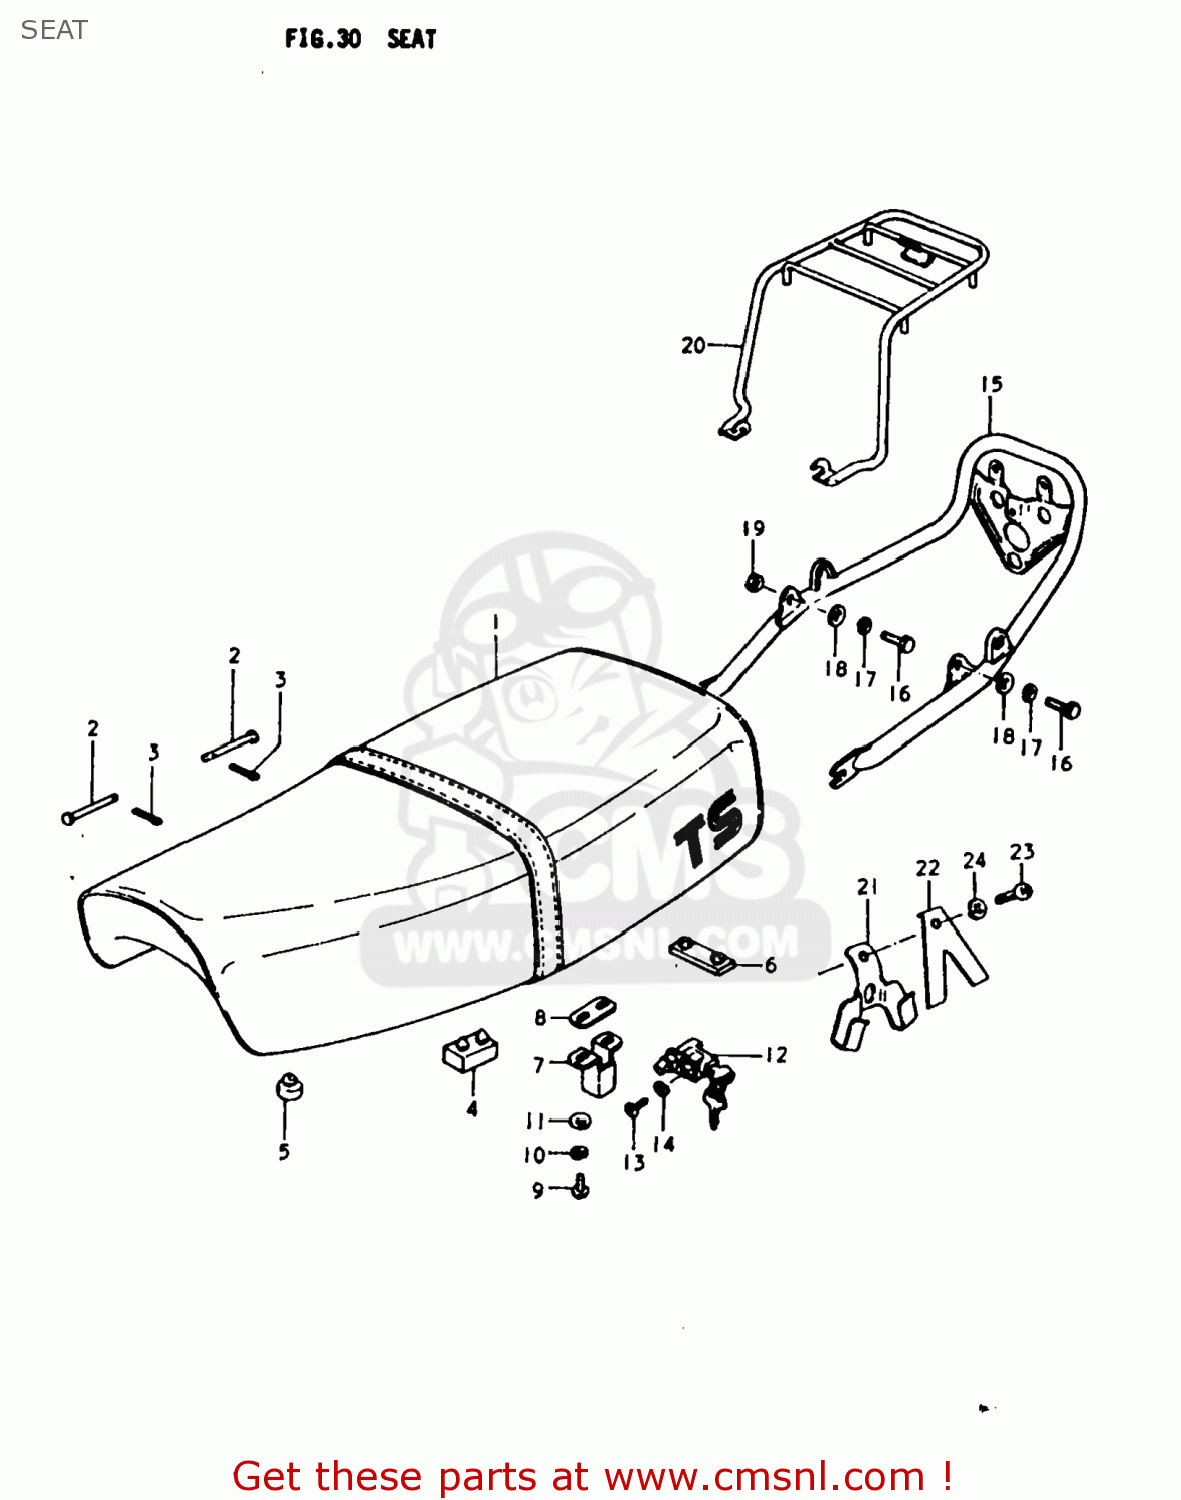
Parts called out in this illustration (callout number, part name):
1	SEAT ASSEMBLY
2	PIN
3	PIN
4	CUSHION
5	CUSHION(11.5X22X20)
6	CUSHION
7	PLATE,CLAMP GUIDE
8	WASHER(8.5X18X1)
9	SCREW 6X12
10	LOCK WASHER
11	WASHER
12	LOCK ASSY,SEAT
13	SCREW
14	LOCK WASHER
15	BAR,REAR COMBINATION LAMP
16	BOLT
17	LOCK WASHER
18	WASHER
19	NUT
20	CARRIER
21	HOLDER,HELMET
22	SPRING OPT
23	SCREW 6X12
24	LOCK WASHER
